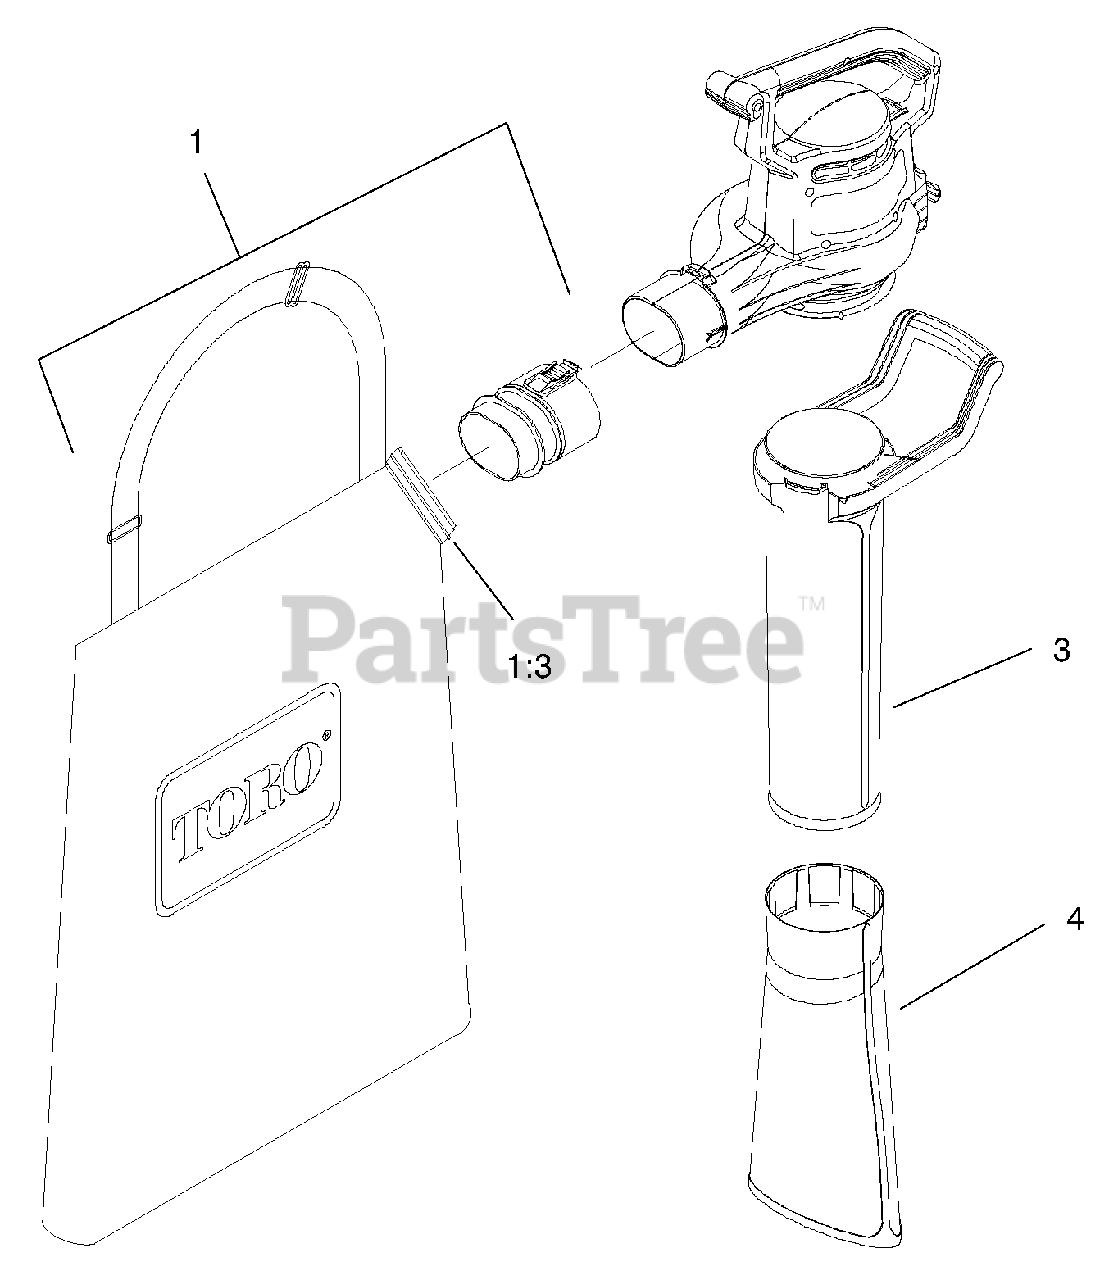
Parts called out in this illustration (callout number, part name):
1:3	Tie-Cable
3	Tube-Vac, Upper
4	Tube-Vac, Lower
